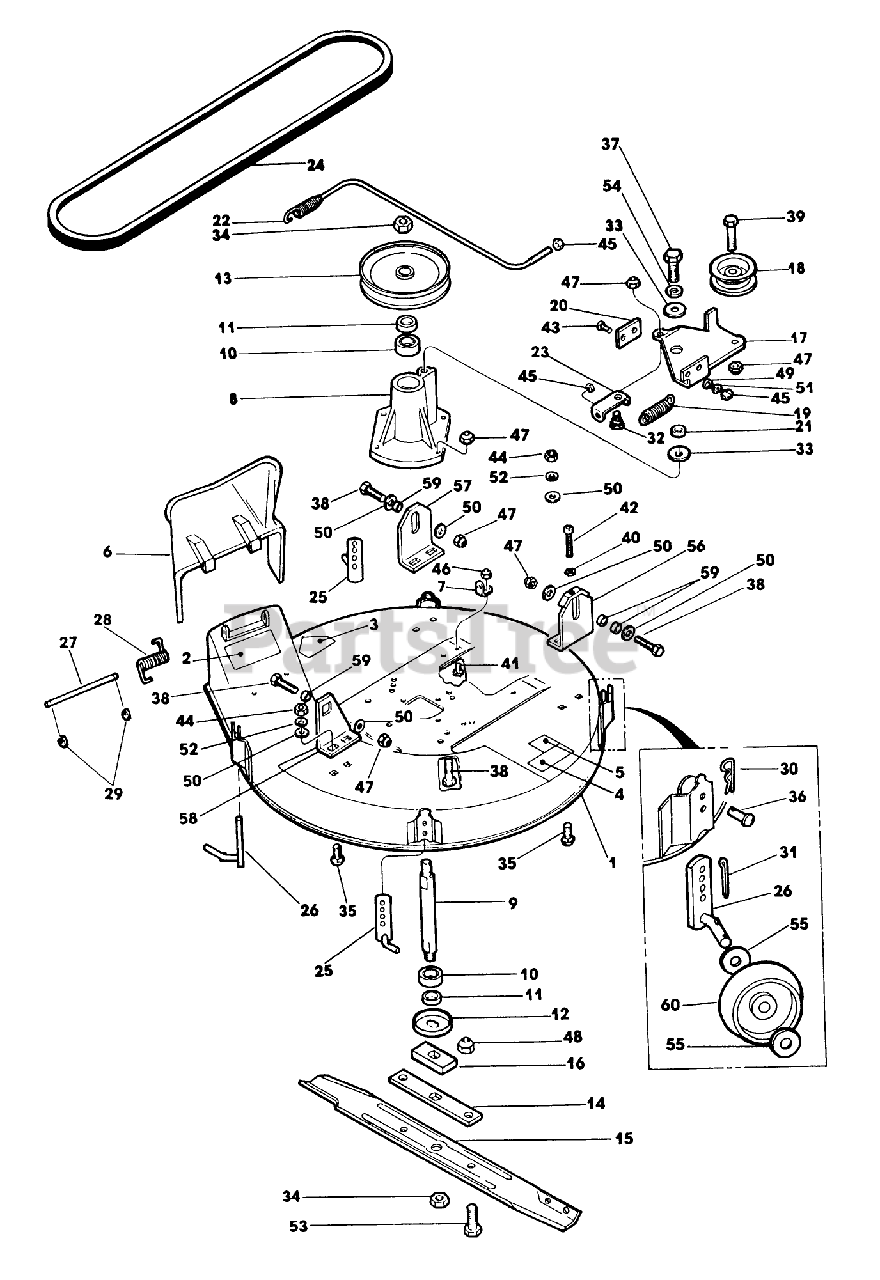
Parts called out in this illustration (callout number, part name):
4	DECAL
6	EXTENSION -CHUTE
8	HOUSING,MOWER SPINDLE
9	SHAFT-SPINDLE
11	SPACER
19	SPRING
24	V-BELT
27	SHAFT - CHUTE
29	E-RING
30	PIN - SPRING CLIP
33	WASHER
34	LOCKNUT-SPECIAL
36	PIN - CLEVIS
41	SCREW-HH
44	NUT
45	NUT
46	NUT-LOCK, CONE
47	NUT-LOCKING
48	NUT-HEX CONE LOK
50	WASHER
52	WASHER
53	SCREW
56	LH REAR HNGR BRKT WA*G
58	BRACKET*G
59	BUSHING
60	WHEEL-GAGE
